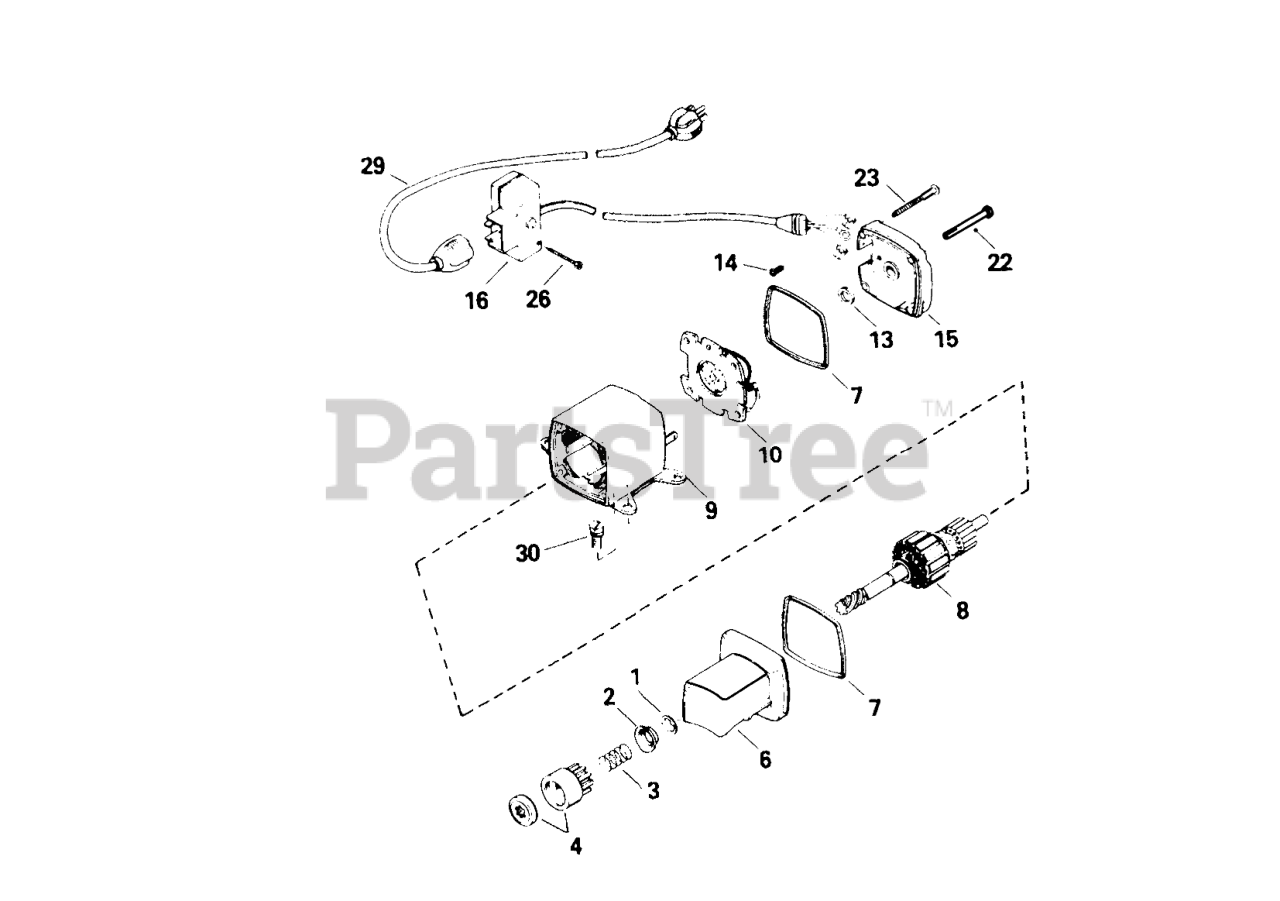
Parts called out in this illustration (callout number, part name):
1	Retainer-Ring
2	Retainer-Spring
3	Spring-Anti Drift
4	Nut & Gear
6	Cap Assembly (Incl. Ref. #7)
8	Armature
9	Housing Assembly
10	Card ASM
13	Washer-Thrust
14	Screw-Ground
15	Cap Assembly (Incl. Ref. #7)
16	Box Assembly-Switch (Incl. Ref. #26)
22	Bolt-Case
23	Screw-Ground
29	Cord-Extension
30	Screw (T-30, 1/4-20 x 23/32)
